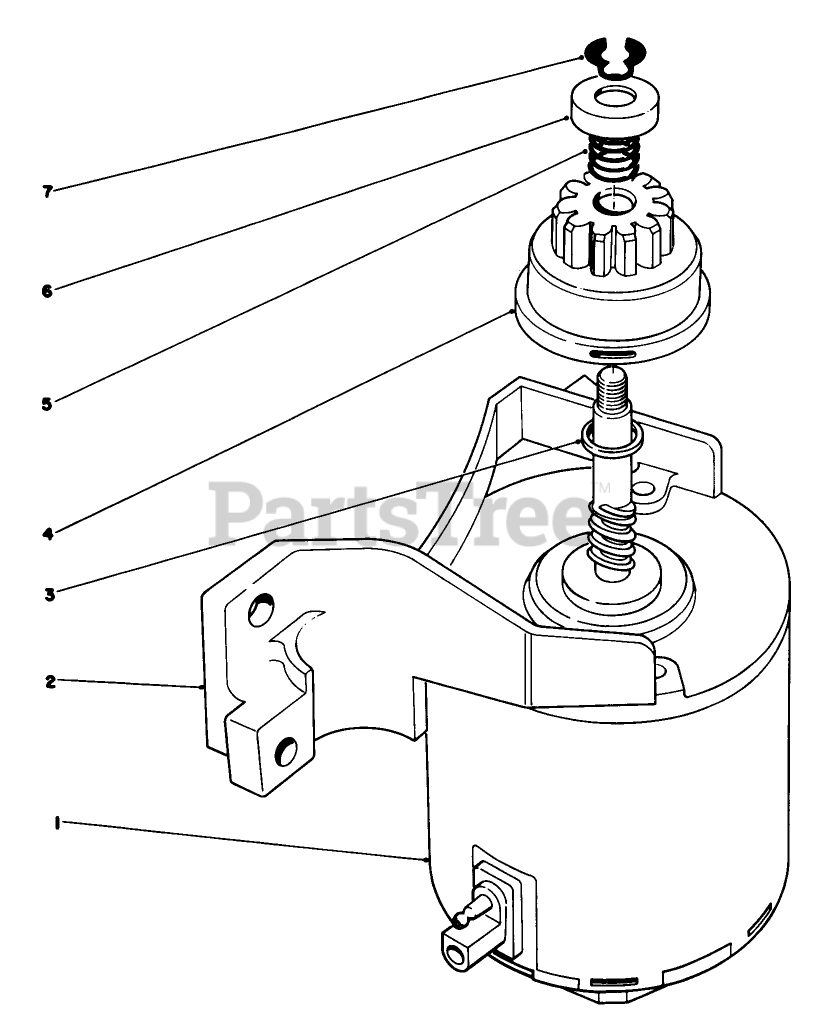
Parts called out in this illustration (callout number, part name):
1	End Frame w/Brushes Electrical Terminal
2	BRKT END FRAME
3	SPACER
4	PINION ASM
5	COMPRESSION SPRING
6	PINION STOP
7	RING-RETAINING
